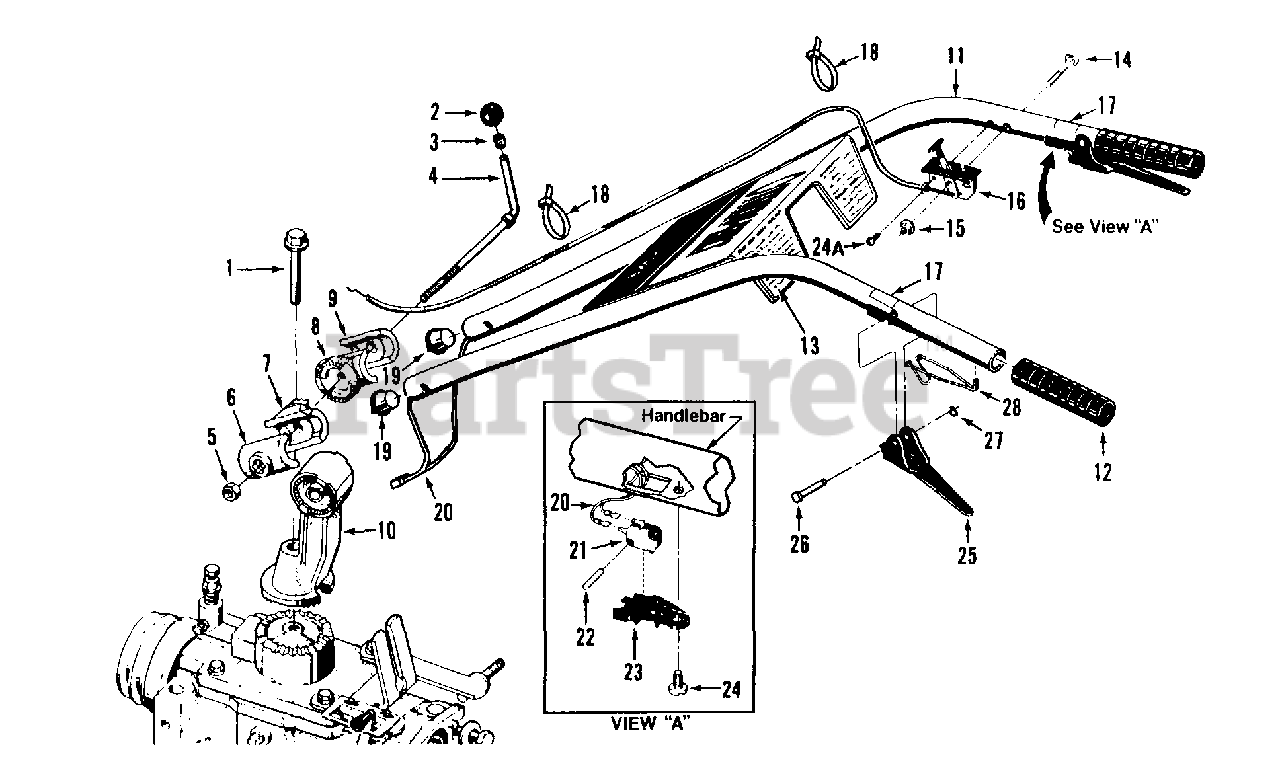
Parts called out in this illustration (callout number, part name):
1	Bolt-Hex hd., flanged self-locking Grade 5, 1/2-13 x 3-1/2"
2	Knob-handlebar height adjustment
3	Ring-retaining
4	Stud-handlebar height adjustment
5	Nut-hex, 1/2"-13
6	Clamp-left, handlebar height adjustment
7	Ratchet-left, handlebar height adjustment
8	Ratchet-right, handlebar height adjustment
9	Clamp-right, handlebar height adjustment
10	Base-handlebar mounting
11	Handlebars
12	Grip-handlebars
13	Decal-operator control panel
14	Bolt-curved hd, GR5, 1/4-20 x 2"
15	Nut-hex, flanged self-locking, whiz lock, 1/4"-20
16	Throttle Control & Cable - 7HP Briggs & Stratton engine only
17	Decal-Forward Interlock Lever
18	Tie-plastic
19	Plug-wire harness retainer
20	Handlebar Wire Harness Assy-forward interlock system
21	Handlebar Switch-forward interlock system
22	Lock Pin-handlebar switch
23	Switch Housing-handlebar switch
24	Screw-pan head, 10-24 x 1/2" thread-forming
24A	Screw-phillips head, 10-32 x 1/2" thread-forming
25	Lever-forward interlock
26	Pivot Pin-forward interlock lever
27	Retaining Ring-klip ring-forward interlock lever
28	Return Spring - fwd interlock lever
